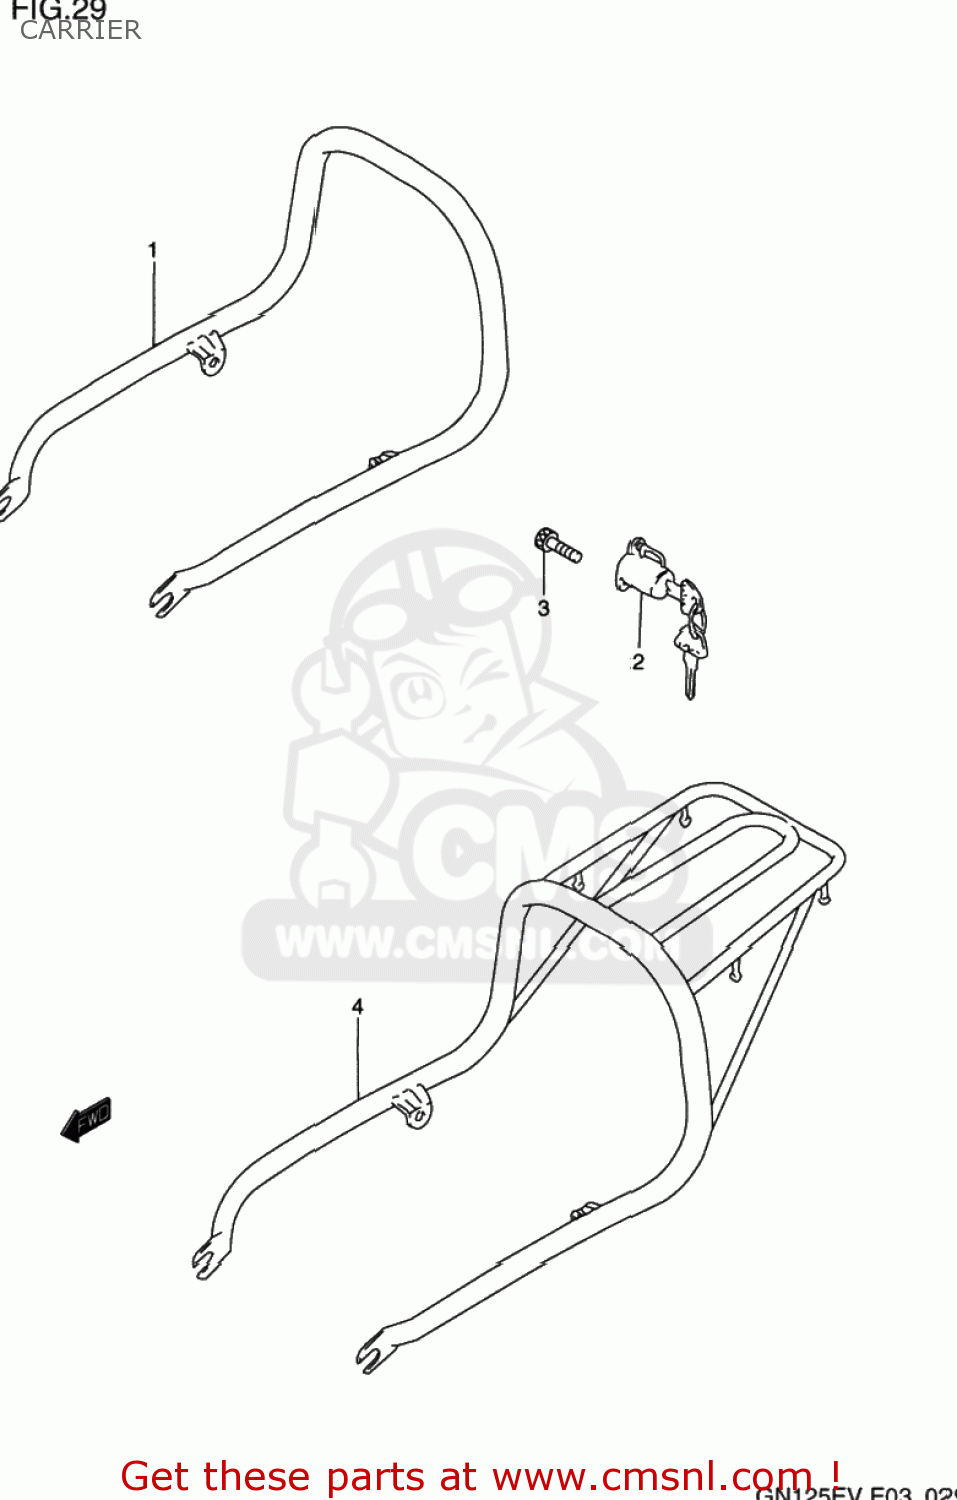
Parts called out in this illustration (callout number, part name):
1	HANDLE,PILLION RIDER
2	LOCK SET,HELMET
3	SCREW(6X12)
4	CARRIER
